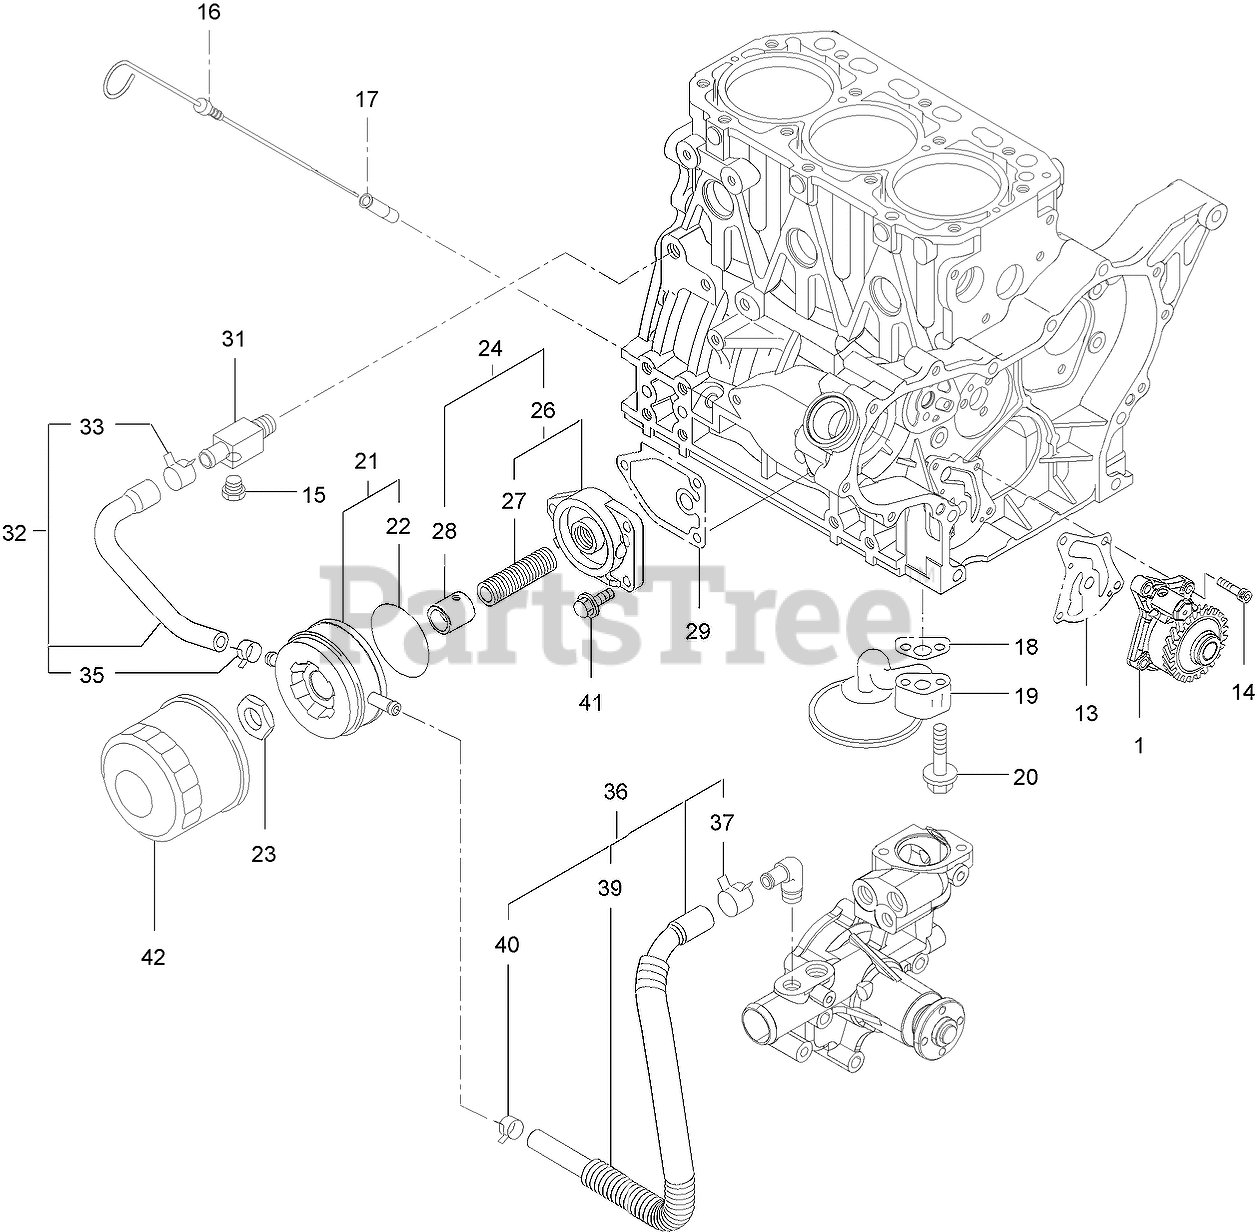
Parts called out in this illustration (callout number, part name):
1	OIL LUBE PUMP ASM
15	PLUG-DRAIN
16	DIPSTICK-OIL
17	GUIDE-DIPSTICK
19	PIPE ASM-OIL INLET
21	COOLER ASM-OIL
22	PACKING-OIL COOLER
24	BRACKET ASM-LO FILT
26	FILTER BRACKET ASM
28	COLLAR-OIL COOLER
32	PIPE ASM
35	CLAMP-HOSE
36	PIPE ASM
40	CLAMP-HOSE
42	FILTER-ENGINE
